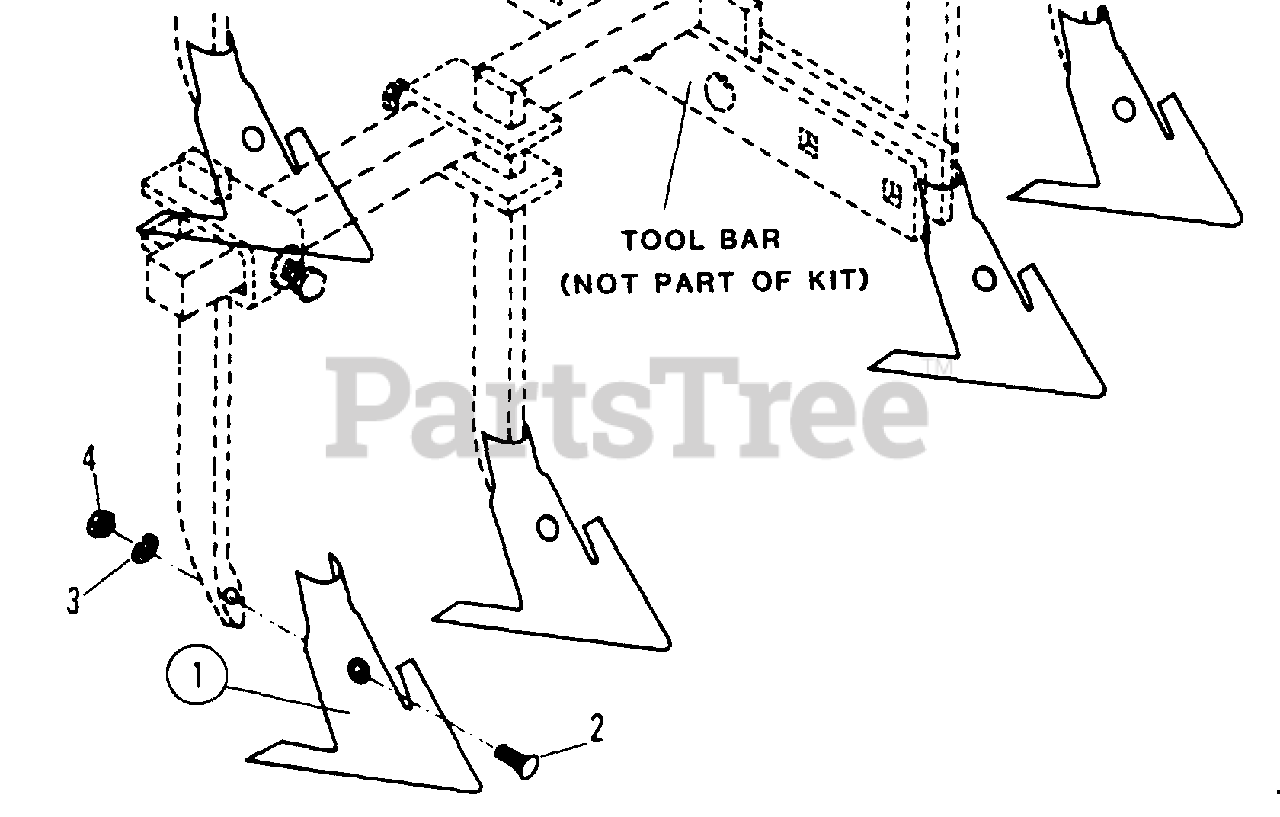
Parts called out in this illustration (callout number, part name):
1	SWEEP, 6 INCH
2	BOLT, 3/8 x 1-1/4 PLOW
3	LOCKWASHER, 3/8
4	NUT, 3/8 HEX
